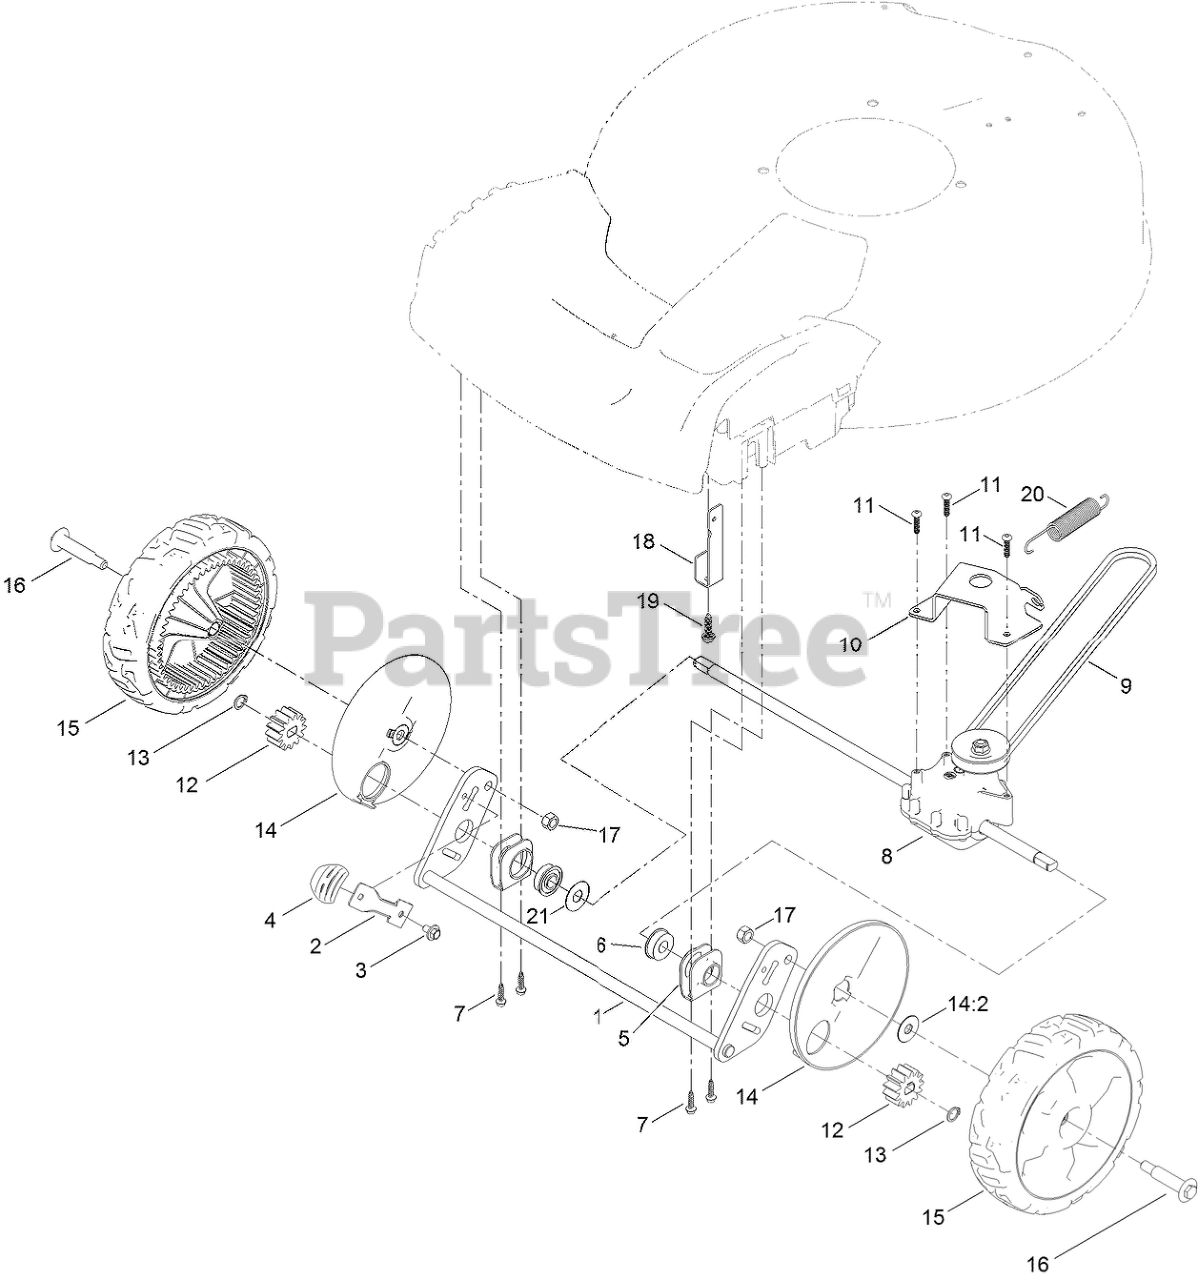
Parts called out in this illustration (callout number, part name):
1	AXLE-FRONT
2	ARM-SPRING
3	SCREW AND WASHER ASM
4	KNOB-LEVER, HOC
5	RETAINER-BEARING
6	BEARING-BALL
7	SCREW-HWH
8	TRANSMISSION-FWD LB, 2BAIL (6:1)
9	BELT-V
10	BRACKET-TRANSMISSION
11	SCREW-PLASTITE
12	GEAR-PINION, 13T
13	RING-RETAINING
14	WHEEL COVER ASM
14:2	WASHER-STEPPED
15	WHEEL ASM, 8IN
16	BOLT-SHOULDER
17	NUT-HEX
18	BRACKET-ANCHOR, CABLE
19	SCREW-FLANGE, PLASTIC
20	SPRING-EXTENSION
21	WASHER-PLAIN
